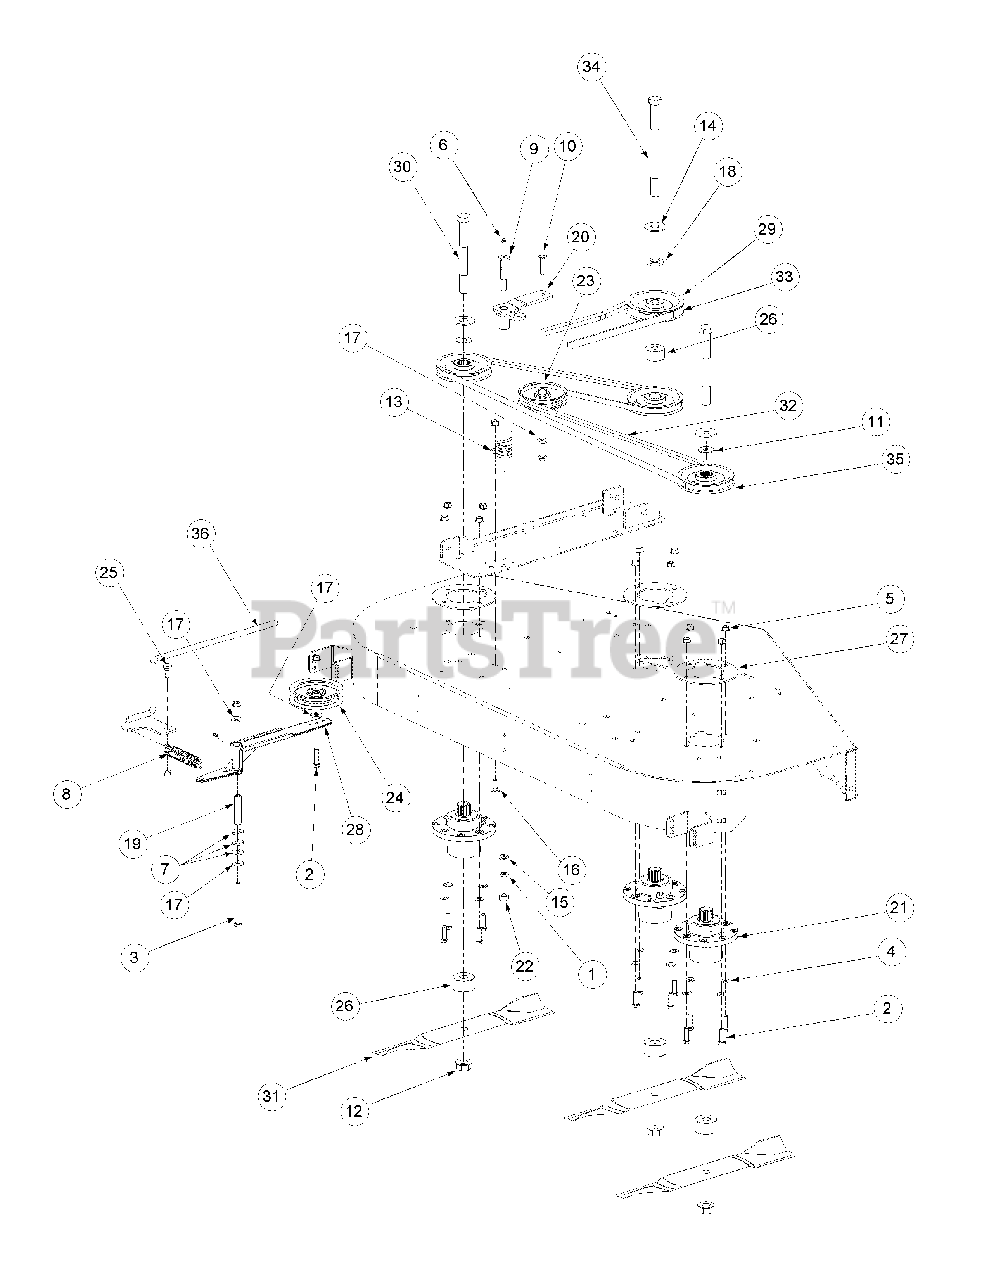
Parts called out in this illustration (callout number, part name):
1	Lock Washer, 7/16
2	Hex Cap Screw, 3/8-16 x 1-1/4
3	Hex Cap Screw, 3/8-16, 4.00
4	Flat Washer, 3/8
5	Hex Nut, Flange Lock, 3/8-16
6	Grease Fitting, 1/4-28 x 3/16
7	Idler Washer
8	Extension Spring, 1.0 OD x 5.125
9	Shoulder Screw, 7/16-14
10	Hex Carriage Screw, 3/8-16, 1.75
11	Spacer, .812 ID x .218 LG
12	Flange Hex Nut, 3/4-16
13	Torsion Spring Idler
14	Flat Washer, .781 ID, 2.00 OD, .105
15	Flat Washer, .469 ID, .875 OD, .105
16	Carriage Bolt, 3/8-16 x 1
17	Flat Washer, .406 ID, 1.0 OD, .105
19	Spacer, .39 ID x .625 OD x 2.75
20	Idler Arm Assembly, Deck Spindle includes:
21	Spindle Assembly, Aluminum Fab Deck
22	Hex Nut, 7/16-14
23	Flat Pulley
24	Idler Pulley, 4.06 OD w/Deep Plan Flanges
25	Shoulder Screw, .50 x .27 LG, 3/8-16
26	Spacer, .760 ID x 2.000 OD x 1.1
27	Plate Support, Cast Aluminum Spindle
28	Idler Arm Assembly, Flat Top Bearing
29	V Pulley, 5.25 OD
30	Hex Cap Screw, 3/4-16, 7.00
31	Hi-Lift Blade, 19.0, 0.756
32	V Belt, A Section x 114.3
33	V Belt, B Section x 87.3
34	Hex Cap Screw, 3/4-16, 9.00
35	V Pulley, 5.00 OD
36	Rod Fab Deck Spring Tension
